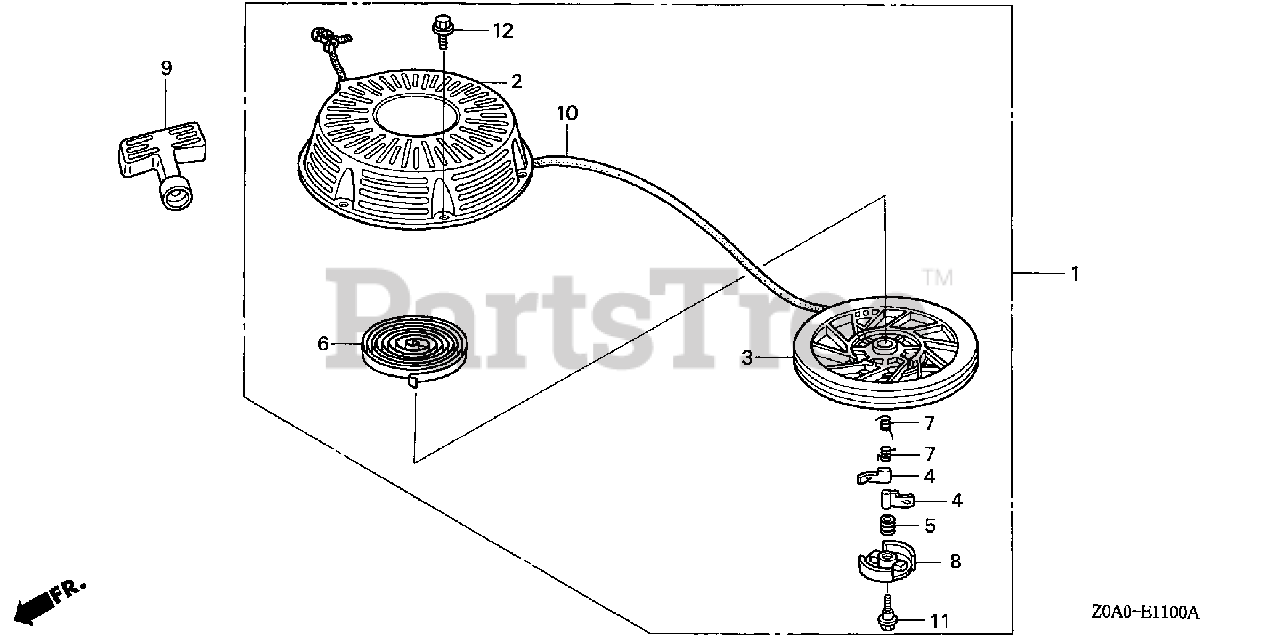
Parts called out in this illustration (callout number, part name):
1	STARTER ASSY., RECOIL *NH105* (MAT BLACK)
2	CASE, RECOIL STARTER *NH105* (MAT BLACK)
3	PULLEY, RECOIL STARTER
4	RATCHET, STARTER
5	SPRING, FRICTION
6	SPRING, STARTER RETURN
7	SPRING, RATCHET
8	RETAINER, SPRING
9	GRIP, STARTER
10	ROPE, RECOIL STARTER (#6X64") (N/A: USE P/N 08560-ZG921-11)
11	SCREW, CENTER
12	BOLT, FLANGE (6X8)
